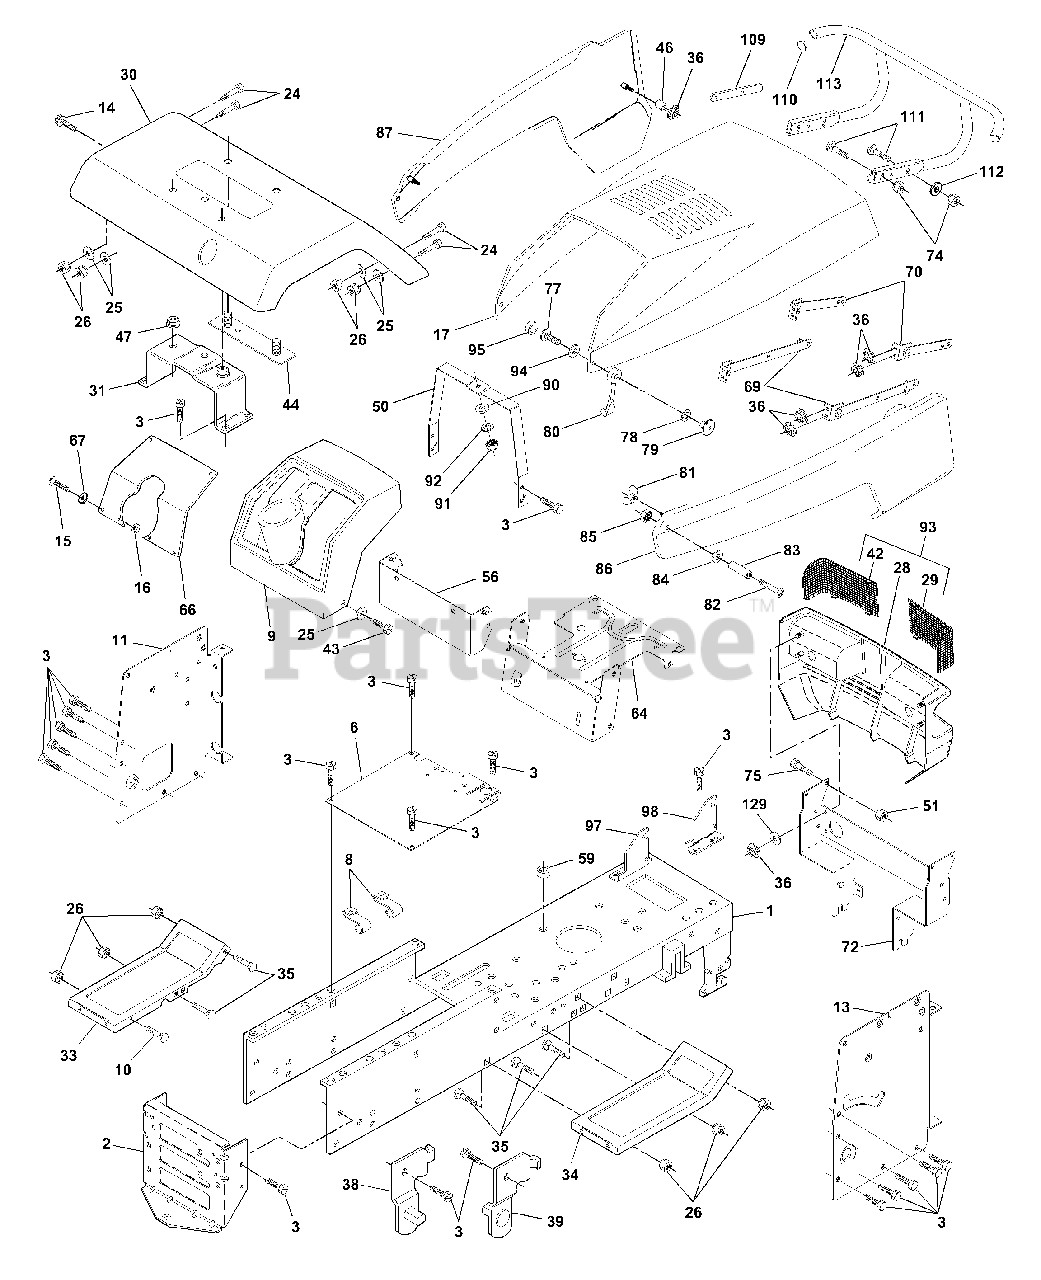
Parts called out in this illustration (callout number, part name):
2	Drawbar
3	Screw, Thdrol 3/8-16 x 3/4
8	Clip, Insulator
10	Bolt, Carriage 3/8-16 UNC x 1
11	Dash Panel, LH
13	Dash Panel, RH
14	Screw, Thd., Roll. 3/8-16 x 1/2
15	Screw, Machine 5/16-18 UNC x 3/4
16	Nut, Hex, Keps 5/16-18 UNC
24	Bolt Fin Hex 3/8-16 UNC x 1 Gr. 5
25	Washer 13/32 x 13/16 x 12 Gauge
26	Nut Lock Hex W/Ins. 3/8-16 UNC
28	Grille
29	Lens, Headlight, RH, Smoked
30	Fender
31	Bracket Fender
33	Footrest, LH
34	Footrest, RH
35	Bolt, Carriage 3/8-16 x 3/4
38	Pivot Bracket Assembly, Rear, LH
39	Pivot Bracket Assembly, Rear, RH
42	Lens, Headlight, LH, Smoked
43	Screw Thdrol 3/8-16 x 3/4 Ty-Tt
44	Strap, Fender
47	Nut, Push, Nylon
50	Support, Dash
51	Nut Lock W/Insert 1/4-20 UNC
56	Extension Dash
59	Bushing, Snap Split
64	Dash, Lower
66	Plate, Dash
67	Washer 11/32 x 11/16 x 16 Gauge
69	Strap Assembly, Hinge, Rear
70	Strap Assembly, Hinge, Front
72	Support Assembly, Grille
74	Nut Crownlock 3/8-16 UNC
75	Bolt, Shoulder 1/4-20 UNC
77	Screw, Machine, Cross Pan Head #10-24 x 1/2
78	Washer, Lock #10
79	Nut, Weld
80	Latch, Chute
81	Wing Nut, Plastic 1/4-20
82	Screw, Machine, Cross Pan Head #10-24 x 1-1/4
83	Spacer, Split #10 x 3/4
84	Washer 7/32 x 1/2 x 18 Gauge
85	Nut, Hex, Keps #10-24 UNC
86	Side Panel, RH
87	Side Panel, LH
90	Washer 9/32 x 3/4 x 16 Gauge
91	Nut Fin Hex 1/4-20 UNC
92	Washer, Lock, Hvy Hlcl 1/4
93	Grill Assembly
94	Washer, Cap
95	Cap, Black
97	Pivot Bracket Assembly, LH
98	Pivot Bracket Assembly, RH
109	Bracket Extension Bumper
110	Plug Plastic
111	Bolt Carriage 3/8-16 x 1-1/4
112	Washaer 13/32 x 13/16 x 16 Ja.
113	Bumper Asm w/Poly Bag
129	Washer 9/32 x 5/8 x 16 Ga.
